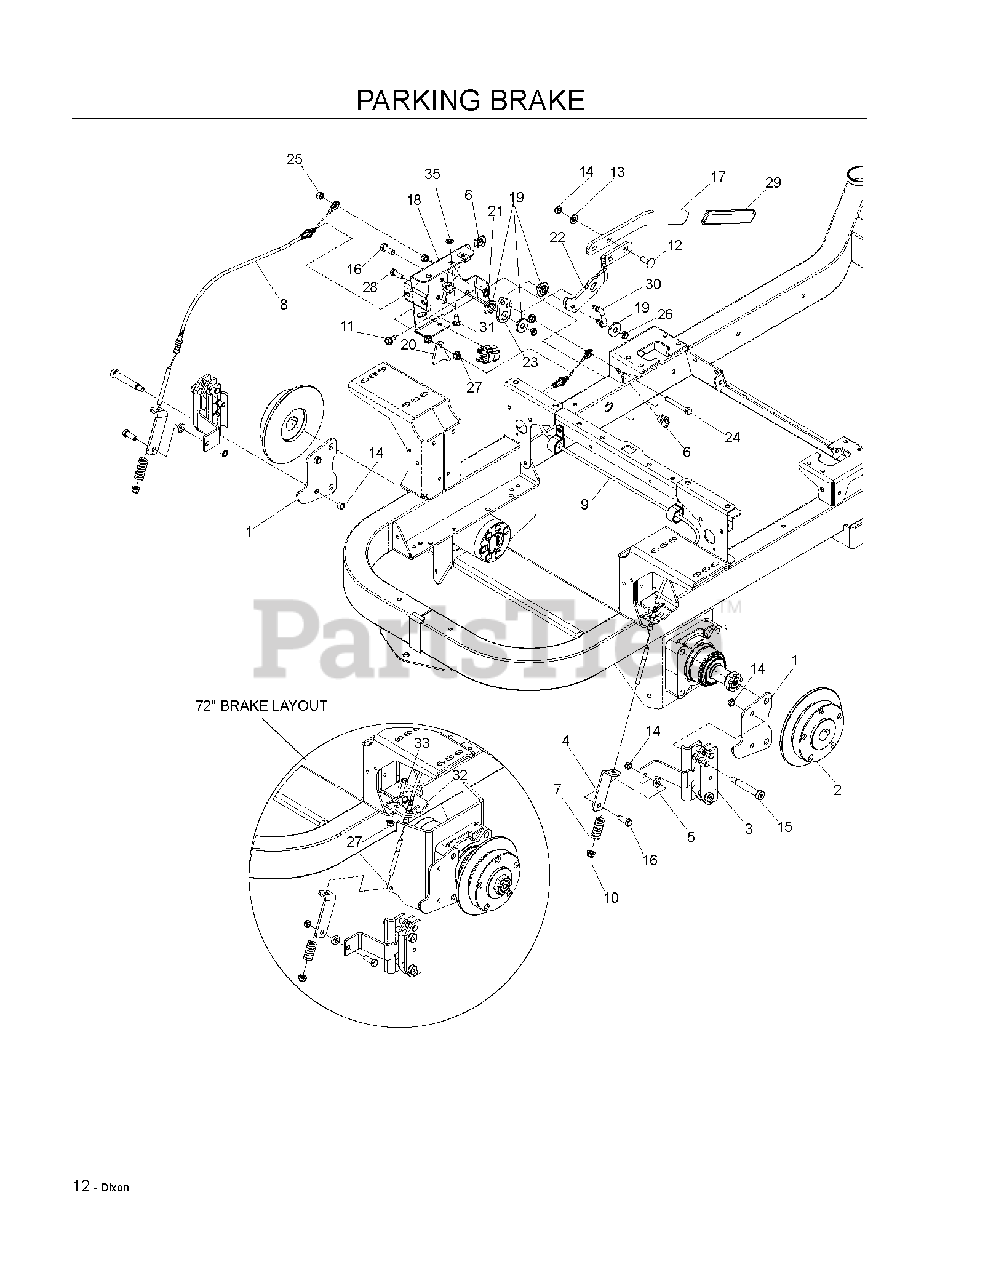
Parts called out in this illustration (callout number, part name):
1	PLATE, BRAKE
2	HUB, 5 BOLT
3	CALIPER PARK BRAKE
4	BRACKET, L
5	WASHER 3/8 X 3/4 X .187 TK
6	U-CLIP 5/16-18 NUT RETAINER
8	CABLE, BRAKE, SHORT
9	CABLE, BRAKE, LONG
10	5/16-18 NYLOC FLANGE NUT
11	BOLT 5/16-18 X 3/4
12	RHSNB 3/8C X 1
13	WASHER 3/8 SAE FLAT
14	NUT HEX 3/8-16 NYLON, THIN
15	SB 3/8-16 X 2-1-1/2 SKT HDD ZD
16	HCS 3/8C X 1
17	ARM, BRAKE, BLK
18	MOUNT, BRAKE WLDMT
19	BUSHING, BRAKE
20	ACTUATOR, SWITCH
21	NUT 5/16C WHIZ
22	LEVER, BRAKE
23	BELLCRANK, BRAKE
24	HCS 5/16-18 X 2 1/2 TPBLT
25	NUT 5/16 NYLOC
26	NUT HEX 3/8-16 NYLON, THIN
27	5/16-18 NYLOC FLANGE NUT
28	HCS 5/16C X 1
29	GRIP BRAKE HANDLE
30	LINKAGE, BRAKE
31	BOLT 5/16C X 3/4" CARRIAGE
32	BRKT, EXTENSION
33	HCS 5/16C X 1
